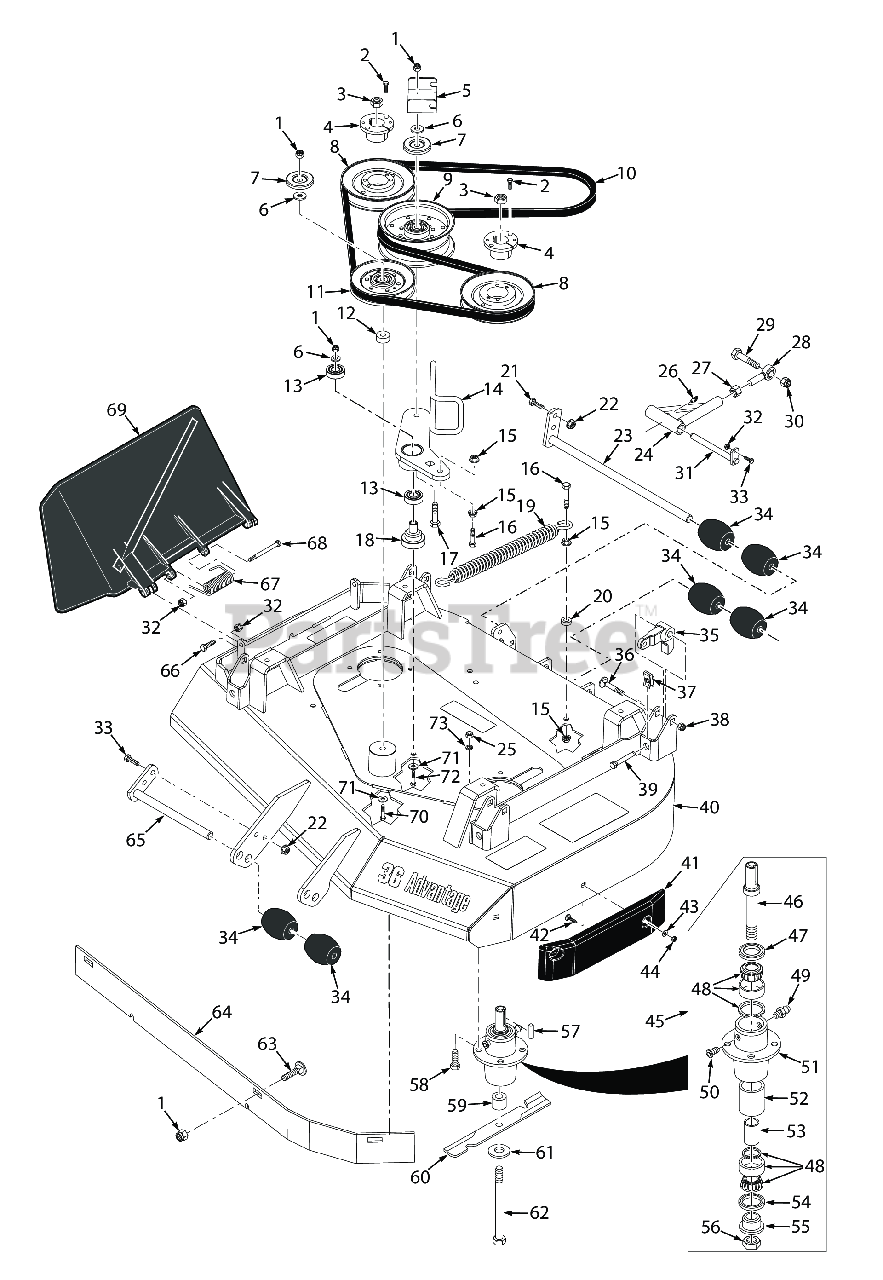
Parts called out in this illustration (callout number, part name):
1	HEX NUT, ELASTIC STOP LOCK, 3/8-16
2	Bolt, Hex Head 1/4-20 x 1" Grade 8 Black
3	Hex Locknut, Elastic Stop, 3/8-16
4	Hub, Tapered 1-1/8" Bore
5	Bracket, Belt Guide
6	Flatwasher, 3/8 (.391 x .938 x .105 HD) Grade 8
7	Quick Pin, 5/16" Dia.
8	Pulley, 5.73 OD Tapered Bore
9	Pulley, Idler 5" Dia.
10	Belt, Cutter Deck
11	IDLER PULLEY, "V" GROOVE
12	SPACER, J PULL ROD
13	BEARINGS, BALL, NEUTRAL RETURN
14	Idler Arm Assembly
15	NUT, 3/8-16 SERRATED FLANGE HEX HEAD
16	Bolt, Hex Head 3/8-16 x 1-1/2" Grade 8 Black
17	Capscrew, Hex Head 3/8-16 x 3.25"
18	Pivot, Idler
19	Spring, Cutter Deck
20	SPACER, IDLER
21	Bolt, Carriage 5/16-18x1" (large frame units only)
22	Nut, Flange Head Elastic Stop 5/16-18
23	Shaft Weldment
24	Pusharm Assembly, LH
24	Pusharm Assemblly, RH
25	Lock Nut, 5/16-18 Elastic Stop Grade 8
26	Grease Fitting, 90 Degree
27	Nut, Hex Head 5/8-18 UNF
28	Rod End, 5/8" Male RH Thread
29	BOLT, HEX HEAD 5/8-11 X 4-1/2"
30	HEX LOCKNUT, ELASTIC STOP, 5/8-11
31	Shaft Weldment, Pusharm Mounting
32	HEX NUT, ELASTIC STOP LOCK, 5/16-18
33	Bolt, Heax Head 5/16-18 x 1" (48V / 52V)
34	Wheel, Anti-Scalp
35	Lever, Deck Level
36	Bolt, Carriage 7/16-14 x 2-1/4"
37	U-Nut, 3/8-16 (short)
38	HEX LOCKNUT, ELASTIC STOP, 7/16-14
39	Bolt, Hex Head 3/8-16 x 2" Special Lock
40	Cutter Deck w/Decals
41	Pad, Deck Wear
42	Bolt, 5/16-18 x .75 RHSN Carriage
43	Flatwasher, 5/16-.344 x .688 x .065 (48V / 52V)
44	Nut, Center Lock, 5/16-18(32)
45	Cutter Spindle Assembly
46	Spindle Shaft, Tapered Brng
47	SEAL, 2.00 O.D. X 1.50 BORE
48	Tapered Bearing Set (Two Bearings W/Race)
49	GREASE FITTING, STR. 1/4-28 SELF TAP.
50	RELIEF FITTING, TAPERED BEARING SPINDLE
51	Housing, Spindle
52	Spacer, Outside, Cutter Spindle
53	SLEEVE, CUTTER SPINDLE
54	Seal, 2.00" O.D. x 1.625" Bore
55	SPINDLE BUSHING, BOTTOM
56	Nut , Spec ial 1 -1/ 1 6 - 1 8
57	Key, 1/4 x 1/4 x 2.0"
58	Bolt, Hex Head 5/16-18 x 1-1/2" Grade 8
59	Spacer, Spindle Bottom
60	Cutter Blade, 18" (52V)
61	Flatwasher, 5/8-.688 x 1-3/4 x .134 HD
62	BOLT, HEX HEAD, 5/8-11 X 9-1/2 GR.5
63	Carriage Bolt, 3/8-16 x 1.0"
64	Baffle, Flange - 36A
65	Shaft Weldment, Guide Roller
66	Bolt, Hex Head 5/16-18 x 1-1/2" - Front
67	Spring, Discharge Chute
68	Bolt, 5/16-18 x 4-3/4" Hex Head
69	Discharge Chute Advantage - Small
69	Discharge Chute Assy. (CA)
70	Bolt, Hex Head 3/8-16 x 4-3/4"
71	Flatwasher, 3/8-.406 x 1-1-1/2 x 7 Gauge
72	Capscrew, Hex Head 3/8-16 x 3.25"
73	Lockwasher, 5/16 (.317 x .586 x .078) Helical Spring
